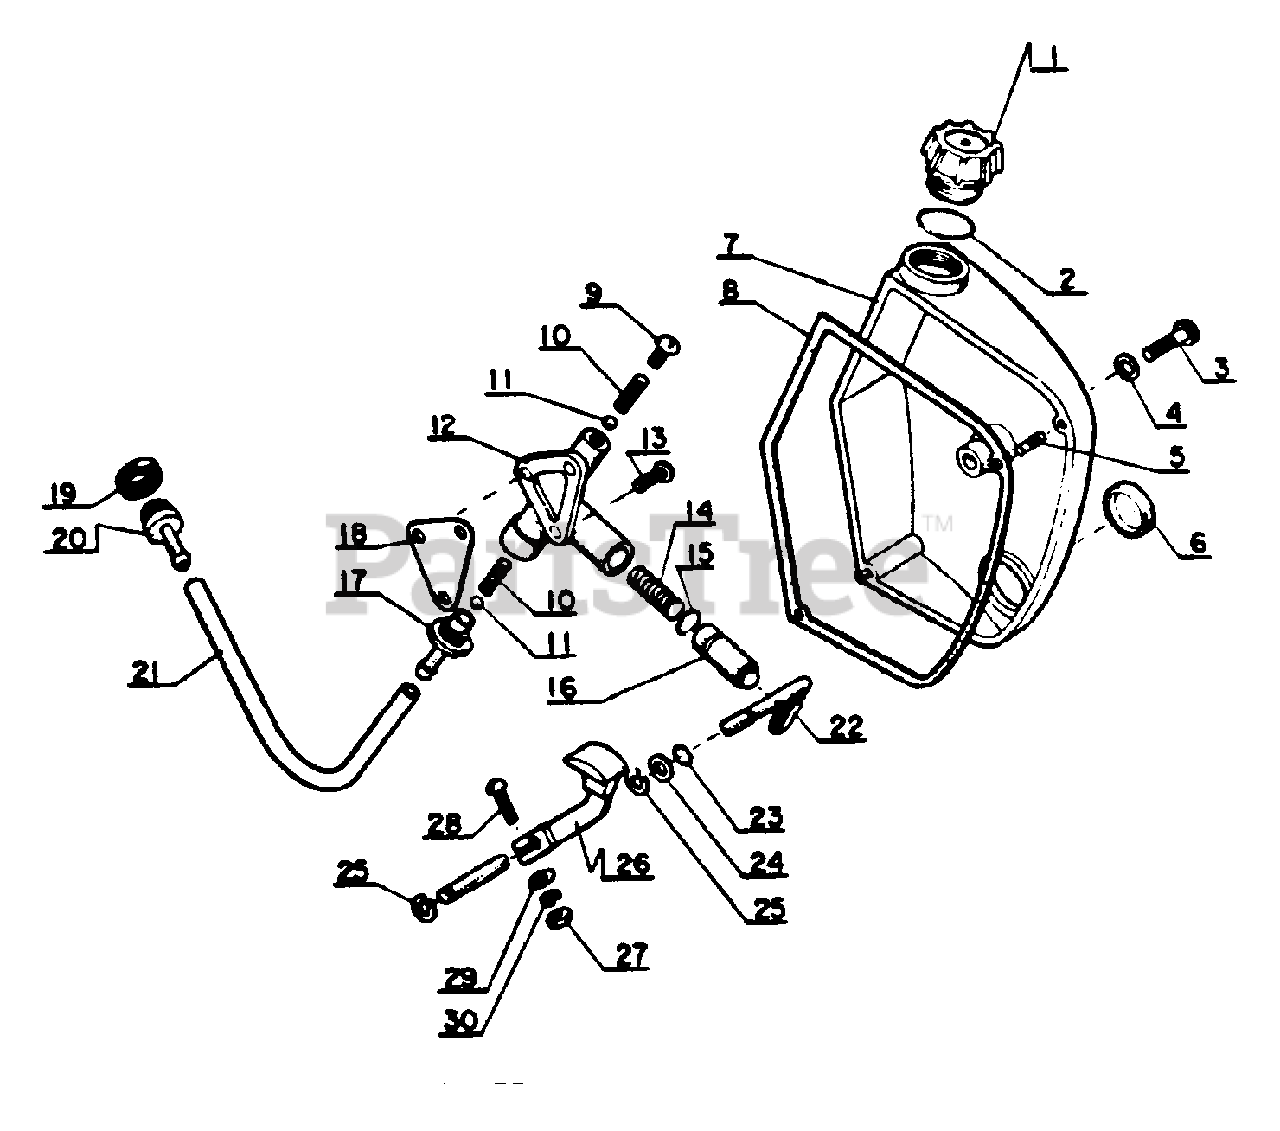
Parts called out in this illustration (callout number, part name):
1	CAP
2	GASKET, CAP
3	BOLT
4	WASHER
5	PIN, DOWEL
6	GAUGE, OIL
7	TANK, OIL
8	OIL TANK PACKING
9	SCREW - 6×5
10	SPRING, VALVE
11	VALVE, BALL
12	BODY, OIL PUMP
13	SCREW
13	SCREW - 5×16
14	PUMP SPRING
15	O-RING
16	PISTON, OIL PUMP
17	NIPPLE
18	PACKING
19	OIL FILTER COVER
20	FILTER, OIL
21	PIPE, OIL - INNER
22	PUSH LEVER
23	O-RING
24	WASHER
25	E-RING 4
26	PUSH LEVER
27	NUT
27	NUT M5
28	SCREW
28	SCREW - 5×14
29	WASHER, FLAT 5.5×10×0.8
30	WASHER, SPRING 5
